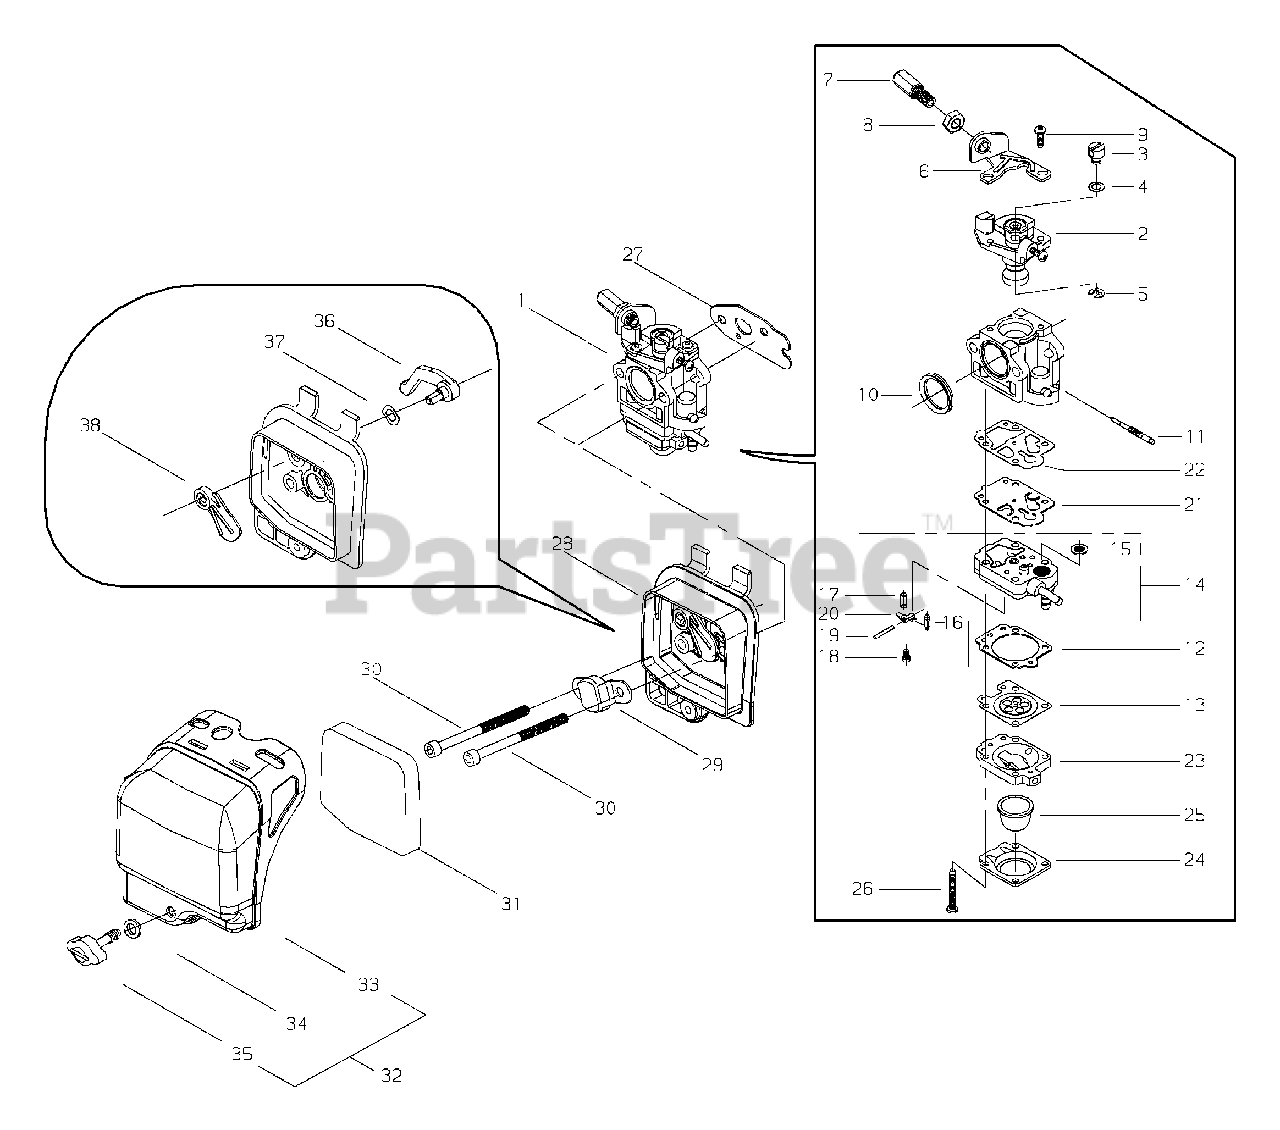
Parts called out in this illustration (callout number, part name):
1	CARBURETOR
2	VALVE ASSY, THROTTLE
3	SWIVEL
4	WASHER
5	E-RING
6	BRACKET, THROTTLE CABLE
7	ADJUSTER, THROTTLE CABLE
8	NUT, ADJUSTER LOCK M7
9	SCREW
10	RING, PACKING
11	NEEDLE, HIGH SPEED
12	GASKET, METERING DIAPHRAGM
13	DIAPHRAGM, METERING
14	BODY ASSY, PUMP
15	SCREEN, FUEL INLET
16	VALVE, INLET NEEDLE
17	SPRING, METERING LEVER
18	SCREW
19	PIN, METERING LEVER
20	LEVER, METERING
21	DIAPHRAGM, PUMP
22	GASKET, PUMP
23	BODY ASSY, PURGE
24	RETAINER, PURGE BULB
25	BULB, PURGE
26	SCREW
27	GASKET, CARBURETOR
28	AIR FILTER CASE ASSY
29	BRACKET
30	BOLT M5×60
31	FILTER, AIR
32	COVER ASSY, AIR FILTER
33	COVER, AIR FILTER
34	WASHER 5
35	THUMBSCREW
36	LEVER, CHOKE
37	WASHER, WAVE
38	PLATE, CHOKE
